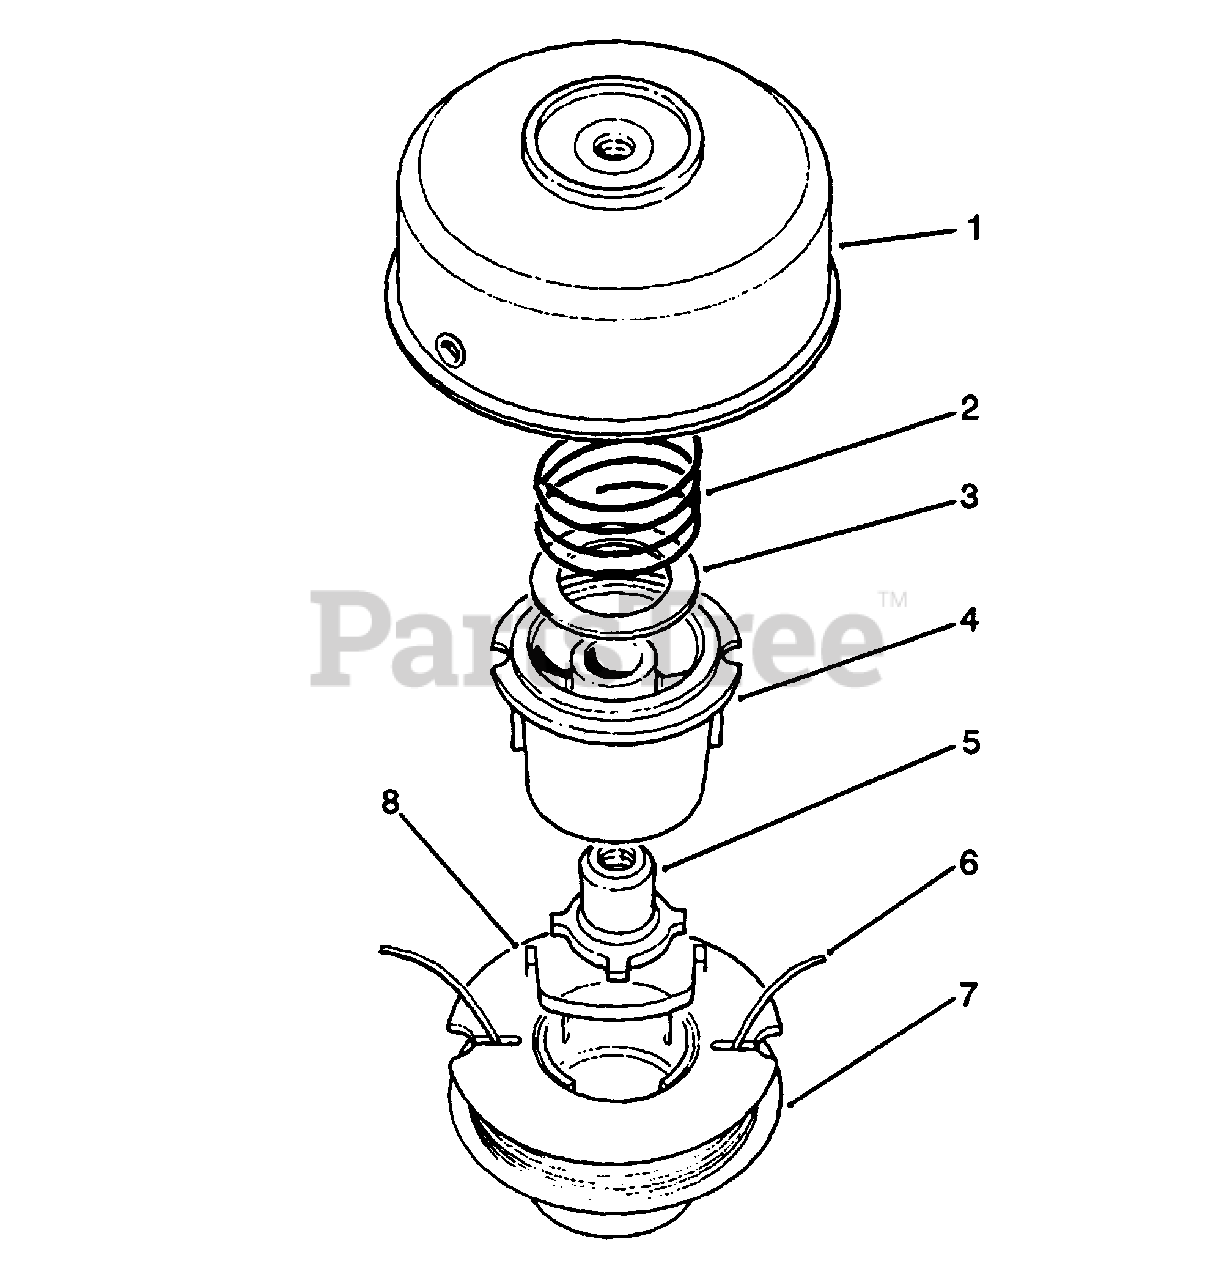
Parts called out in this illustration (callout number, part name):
1	Drum w/Eyelets
4	Spool Core
5	Driver L.H.
6	Line-Cutting .08 Dia. 38'
7	Spool Prewound .08 Dia. 38' (Incl. Ref. #6 & 8)
